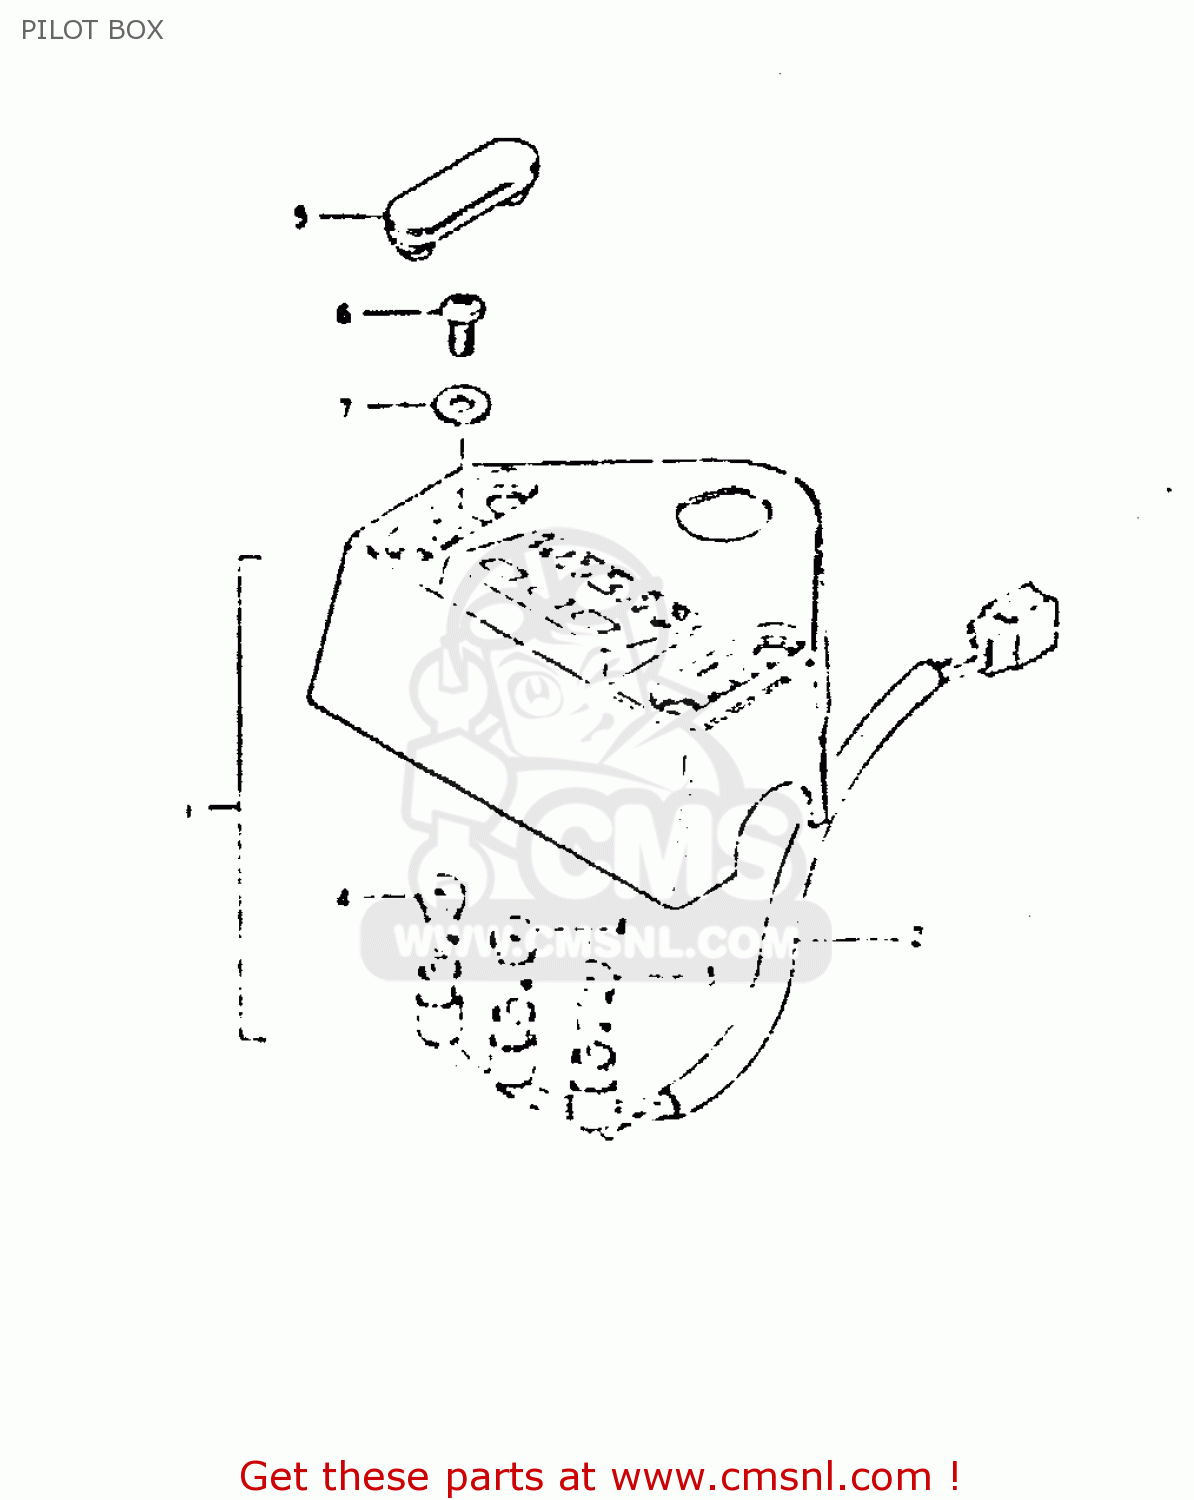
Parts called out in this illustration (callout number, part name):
1	CASE,PILOT BULB
2	SOCKET
3	BULB(6V1.7W,STANLEY,A61A)
4	BULB(6V/3W)
5	CAP,PILOT BOX BOLT
6	SCREW 6X12
7	WASHER
